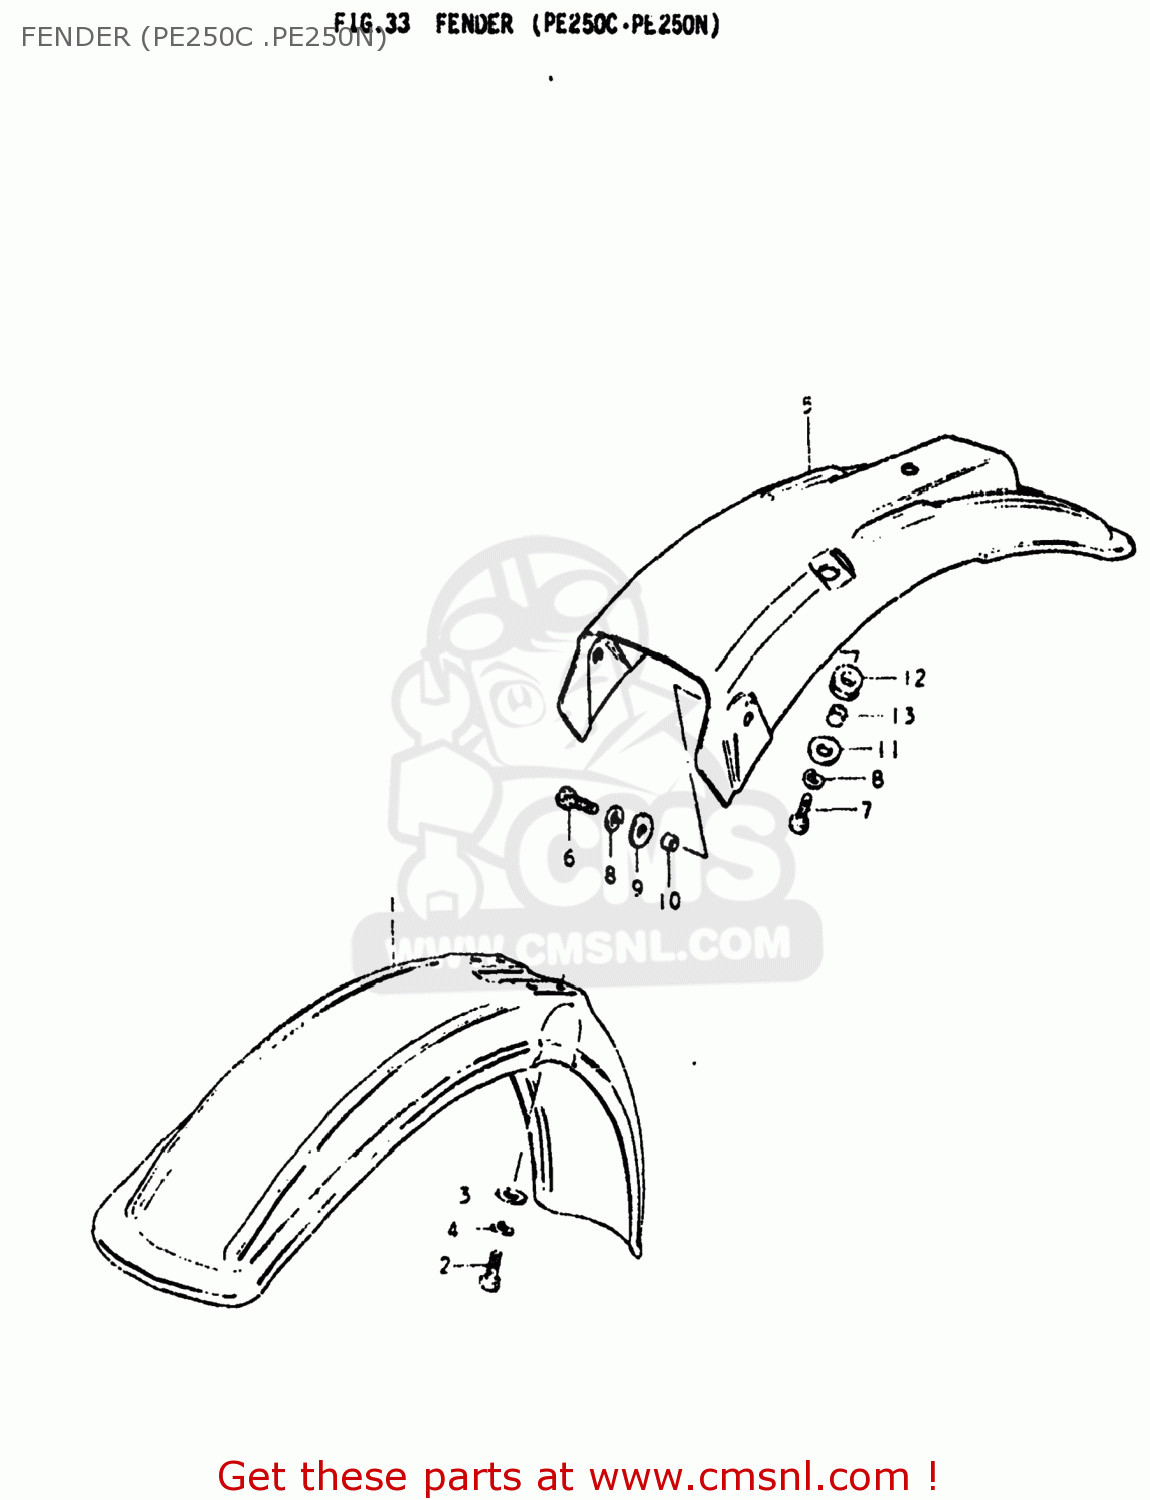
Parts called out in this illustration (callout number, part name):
1	FENDER,FRONT
2	BOLT, UPPER
3	SPACER
4	LOCK WASHER
5	FENDER,REAR
6	BOLT, UPPER
7	BOLT
8	LOCK WASHER
9	WASHER
10	SPACER (6.1X8X5.2)
11	WASHER (6.5X24X1.6)
12	CUSHION
13	SPACER
